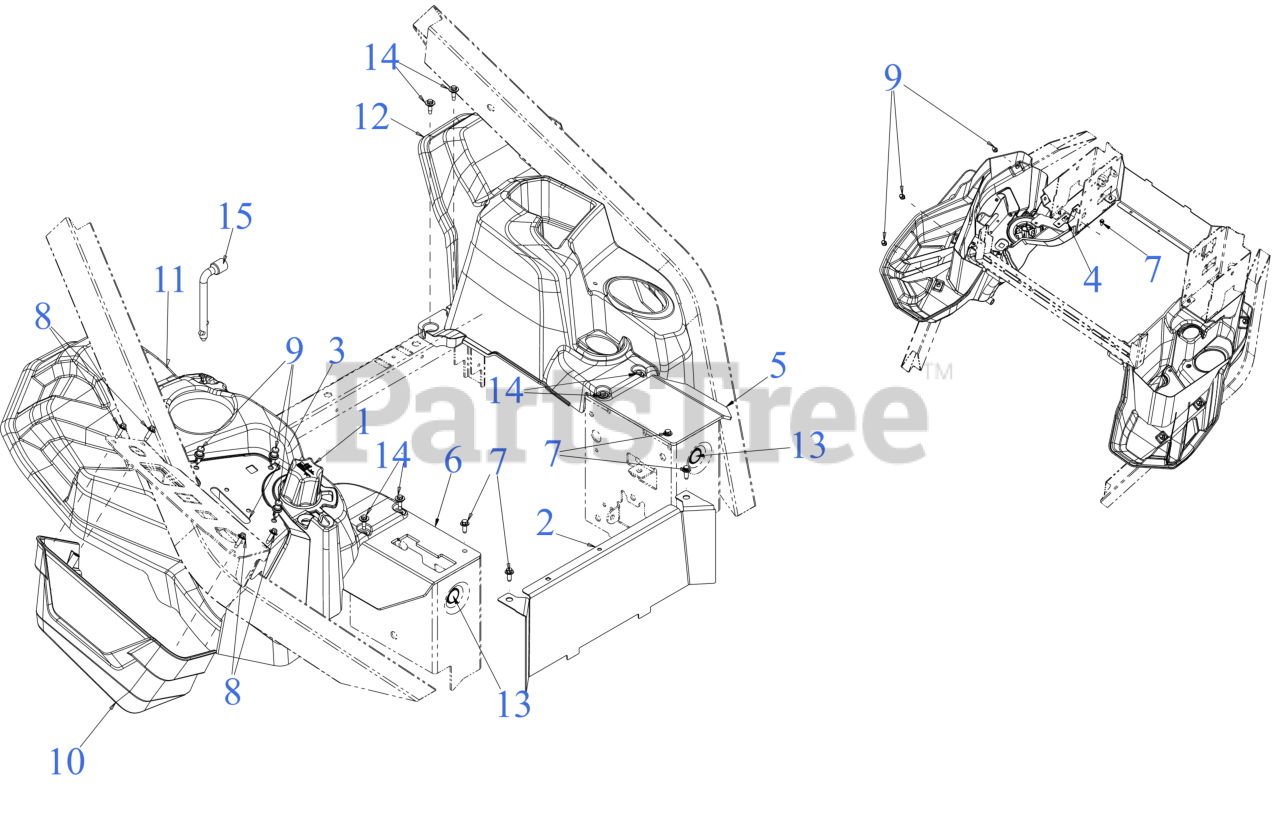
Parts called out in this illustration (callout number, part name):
1	DECK HEIGHT ADJUSTMENT KNOB
2	SEAT BOX FRONT PLATE
3	THROTTLE COVER PLATE
4	SWITCH BRACKET (PARK BRAKE)
5	CONTROL BRACKET (LH)
6	CONTROL BRACKET (RH)
7	SCREW M6-1 x .625
8	SCREW 1/4-10 x .750
9	PLASTIC RIVET
10	CONTROL PANEL CONSOLE
11	CONSOLE (RH)
12	CONSOLE (LH)
13	HOLE PLUG 1.0 OD
14	SHOULDER SCREW M6-1 .368 X.115
15	MULTI TOOL 1/2" SOCKET
